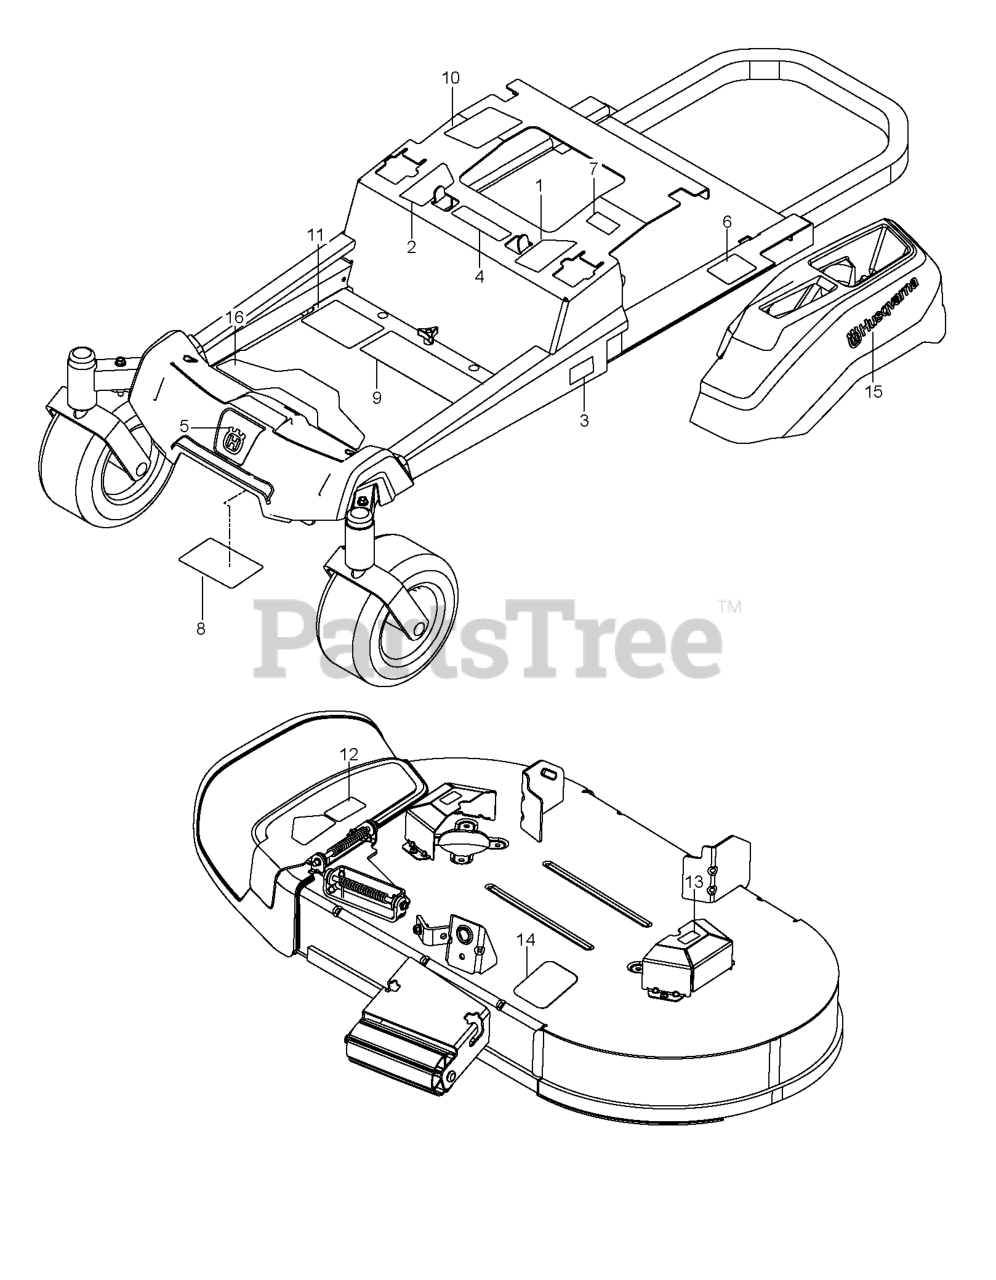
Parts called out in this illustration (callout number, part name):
1	DECAL.ZTR.RZ.THRTL/PRKBRK.V2.L
2	DECAL.ZTR.RZ.THRTL/PRKBRK.V2.R
3	DECAL.ZTR.SIDRAIL.Z242F.HUS
4	EURO DECAL-BATTERY WARNIN6
5	DECAL.BADGE.55MM.CROWNH.HUSQ
6	DECAL, DO NOT TOW
7	DECAL, EXITING MOWER
8	DECAL, SERVICE
9	DECAL, SAFETY WARNING
10	DECAL.WARNING.CUST.RESP.E85.
11	DECAL.ZTR.STARTINS.READYSTART
12	DECAL.TRACT/ZTR.DECKWARN.HUSQ
13	DECAL.DECK.6MIL.EURO.NOSTEP
14	DECAL.V-BELT.SCH.42/46"MEC/ELE
15	DECAL.HUSQVARNA.210MM
16	PAD.RZ.FOOTREST.PLATE
